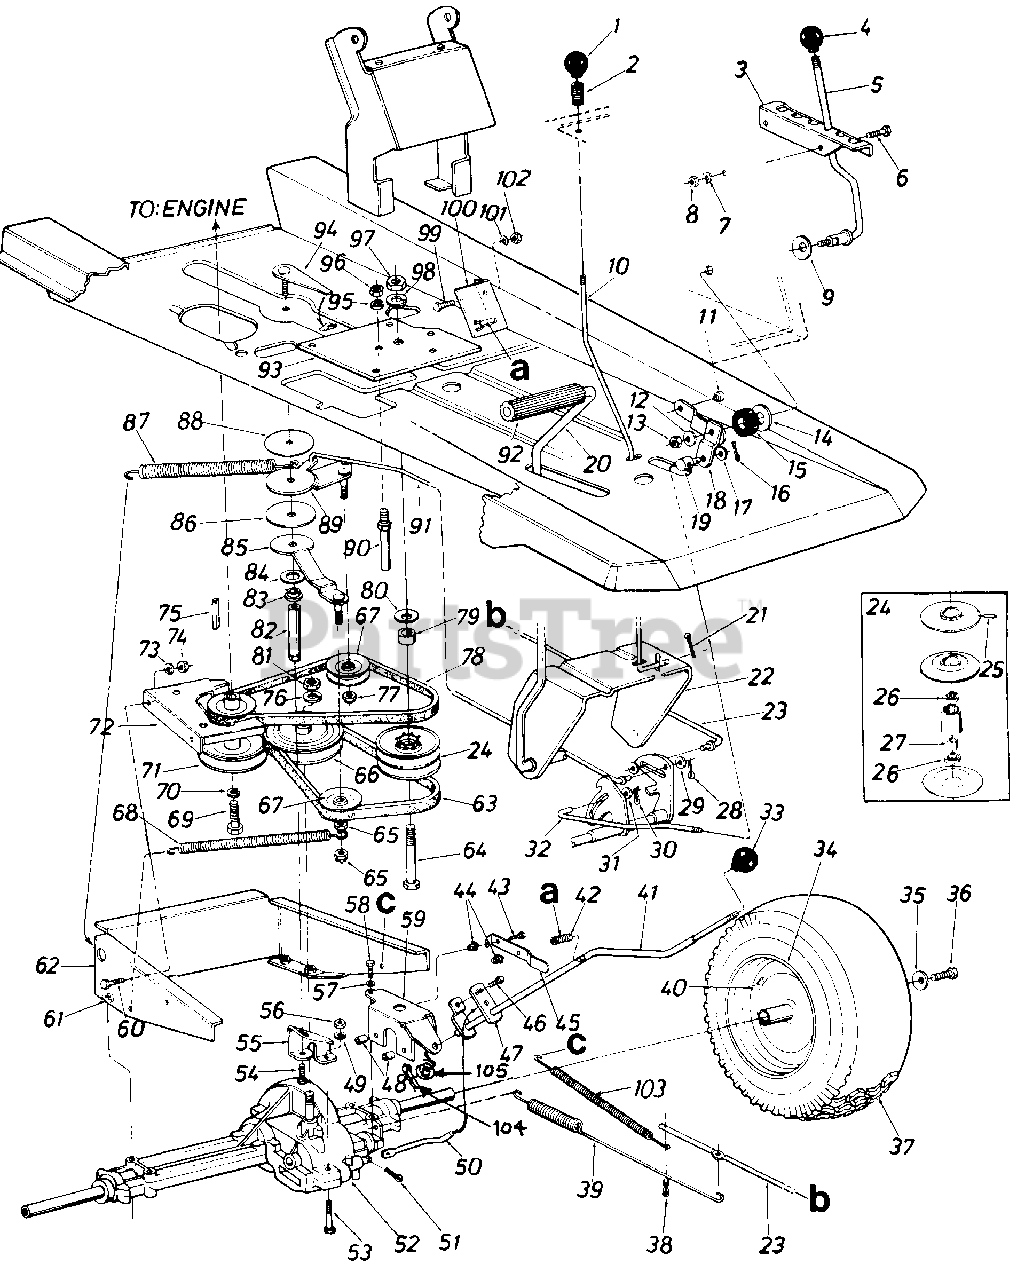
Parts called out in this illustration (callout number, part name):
2	SPRING-COMPRESSION
5	LEVER-SPEED CONTROL
6	SCREW-TRUSS MACH 5/16-18 X .75
7	WASHER-LOCK-5/16
8	NUT-HEX 5/16-18
9	WASHER-BELL .505 ID X 1.00 OD
10	ROD-BRAKE LOCK
12	WASHER-BELL .337 X .867 X .057
13	NUT-HEX CENTER L-5/16-18
14	WASHER-SPEC 503 X 1.56 X .036
15	WASHER-RUBBER
16	PIN-INTERN COT
17	WASHER-FL (#46041)
18	BRACKET ASSY
19	FERRULE
20	PEDAL ASSY-BRAKE
21	PIN-COTTER-3/32 DIA X .75
22	PEDAL ASSY-BRAKE
23	ROD-BRAKE
24	PULLEY ASSY-VAR SP
25	PIN-SPRING SPIR 5/32 X .62
26	BEARING-BALL
28	PIN-COTTER-1/8 DIA X 1.00
29	WASHER-FL (#46041)
30	PIN-INTERN COT-5/16 DIA
31	WASHER-FL (#46041)
32	LINK-SPEED CONTROL
33	KNOB-BALL 1-3/8 " DIA.
35	WASHER-BELL .337 X .867 X .057
36	SCREW-CAP LOCK 5/16-24 X .75
38	PIN-COTTER-1/8 DIA X 1.25
39	SPRING-EXTENSION
40	VALVE-TUBELESS AIR
43	SCREW-C SINK #8X.50
45	SPRING-SWITCH
46	SCREW-HEX 1/4-20 X .50
47	LINK-SHIFT LEVER ADJ
49	LOCK WASHER 1/4 DIA
50	ROD-SHIFT
51	PIN-COTTER
52	TRANSAXLE
53	SCREW-HEX 1/4-20 X 1.75
54	SCREW-HEX 3/8-24 X .75
55	BRACKET-TORQUE ROD
56	NUT-HEX 1/4-20
57	LOCK WASHER 1/4 DIA
58	SCREW-SELF TAP MACH 1/4-20X1.37
59	BRACKET-SUPPORT
60	SCREW-HEX 1/4-20 X 1.00
61	NUT-HEX 5/16-18
62	SUPPORT ASSY-TRANS
63	BELT-V 5/8 X 38
64	SCREW-HEX 1/2-13 X 4.0
65	NUT-HEX INS L-3/8-24
67	PULLEY-V-BELT IDLER
68	SPRING-EXTENSION
69	SCREW-HEX 7/16-20 X 1.00
70	WASHER-LOCK-7/16
72	GUARD-ENG BELT-UPR
73	LOCK WASHER 1/4 DIA
74	NUT-HEX 1/4-20
75	KEY-SQ 1/4 X 2.00
76	WASHER-LOCK-1/2
77	NUT-HEX INS L-3/8-24
78	BELT-5LX35.25
80	WASHER-BELL .505 ID X 1.00 OD
81	NUT-HEX 1/2-13
82	ROD-TORQUE
83	BEARING-FLANGE
84	WASHER-FL-.640ID X 1.24OD X .06HDN
85	BRACKET ASSY-IDLER
86	WASHER-THRUST
87	SPRING-EXTENSION
88	WASHER-THRUST .038ID X 3.5 X .015
89	BRACKET ASSY-IDLER
90	ROD-BELT GUARD
91	ROD-CLUTCH
92	PAD-FOOT
93	BRACKET-VAR SP MTG
96	NUT-HEX 1/4-20
97	NUT-HEX 1/2-13
98	WASHER-LOCK-1/2
99	SCREW-HEX 5/16-18 X .75
100	BRACKET
101	WASHER-LOCK-5/16
102	NUT-HEX 5/16-18
103	SPRING-EXTENSION
104	PIN-COTTER-3/32 DIA X .75
105	WASHER-FL-.469 ID X .88 OD X .063
